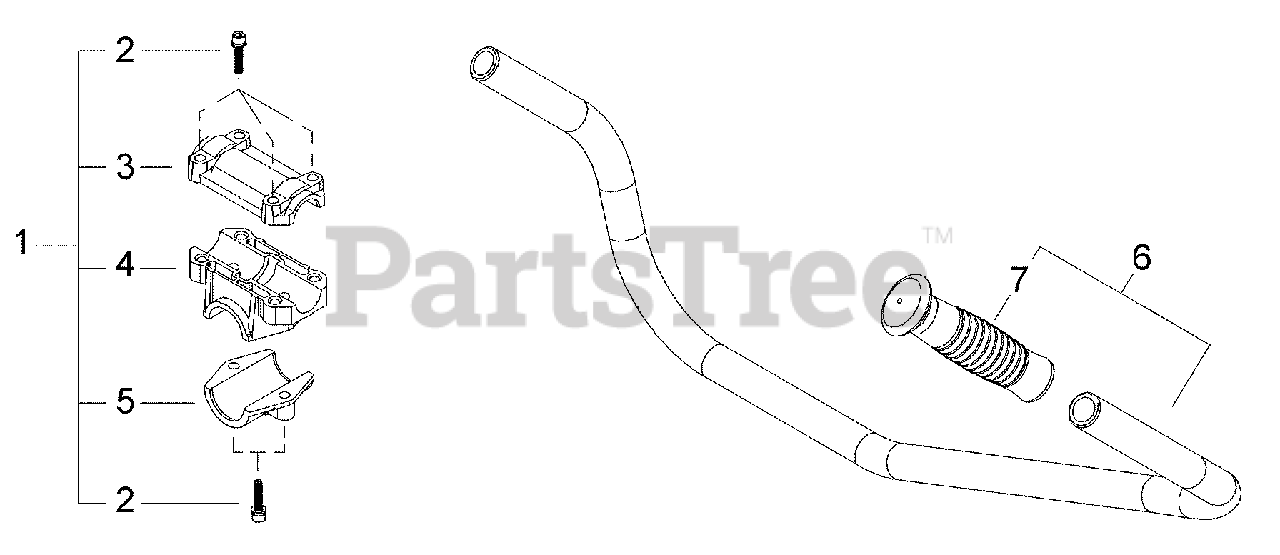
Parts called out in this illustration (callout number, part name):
1	BRACKET KIT, HANDLEBAR
2	BOLT M5×25
3	BRACKET, UPPER HANDLEBAR
4	BRACKET, LOWER HANDLEBAR
5	BRACKET, MOUNTING
6	HANDLEBAR ASSY
7	GRIP
